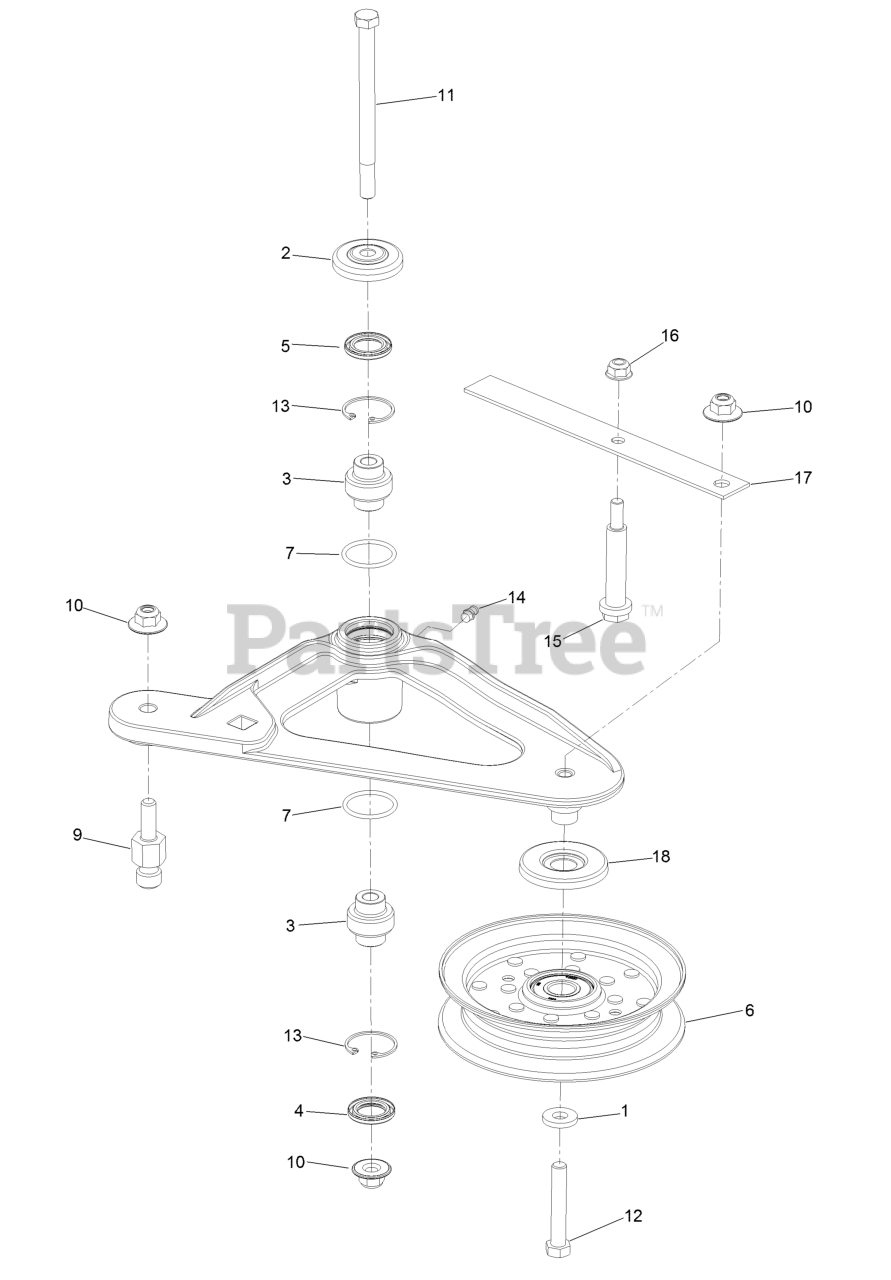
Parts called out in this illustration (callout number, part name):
2	Guard-Top
3	Bearing-Spherical
4	Seal-Lip, Double
5	Seal-Lip, Single
6	Idler-Pulley, Flat
9	Pin-Spring, Anchor
10	Nut-Flange, NI
11	Screw-Shoulder, HH
12	Screw-HH
13	Ring-Snap
14	Fitting-Grease
15	Bolt-Shoulder
16	Nut-HF, NI
17	Spring-Belt
18	Shield-Guard, Dust
